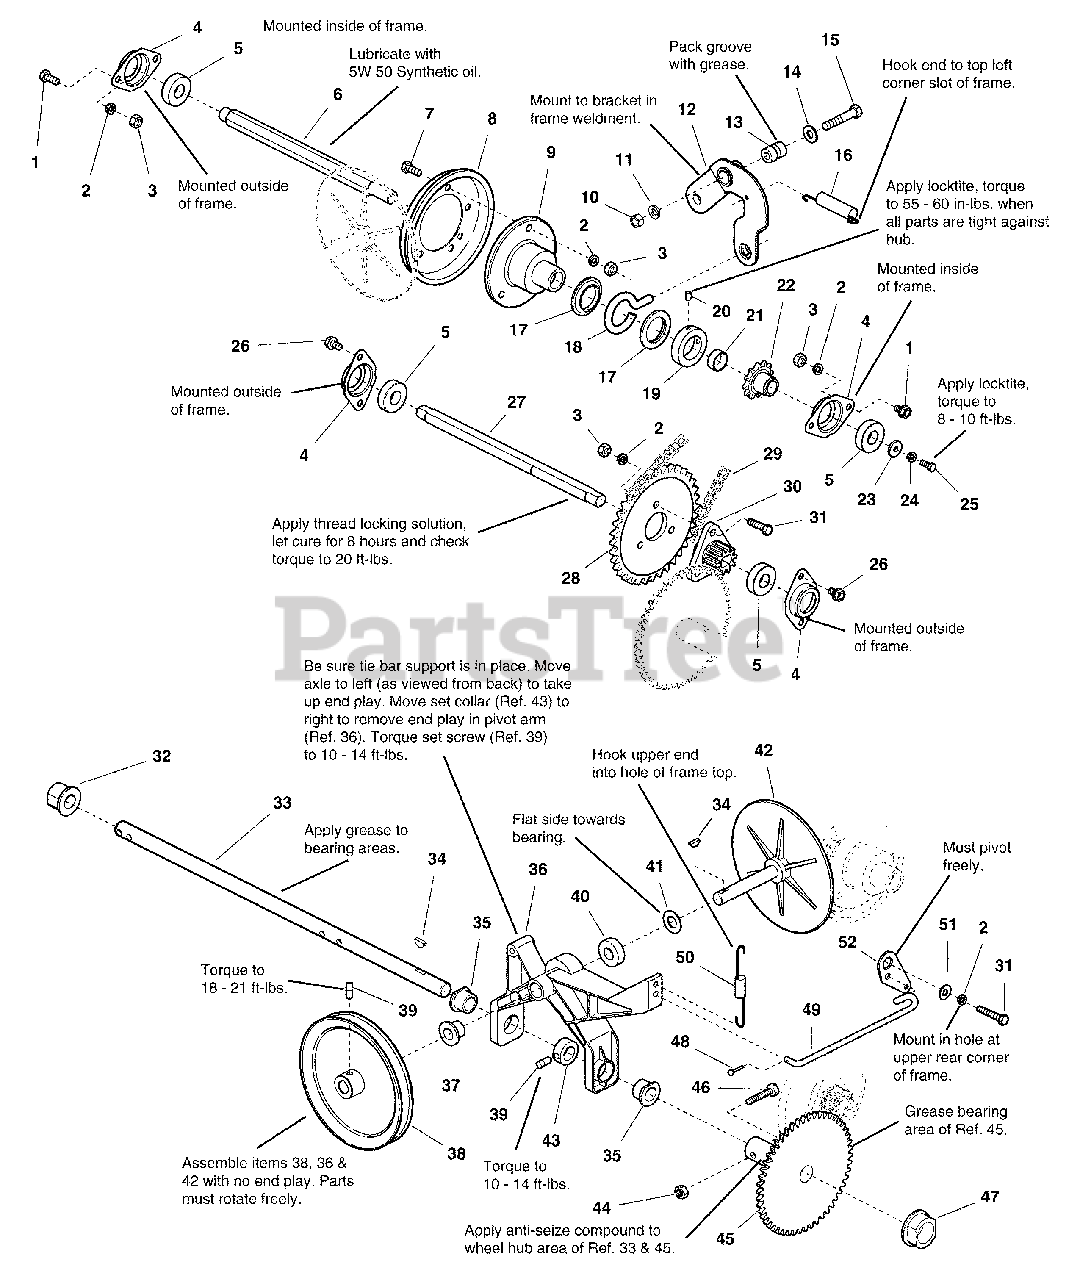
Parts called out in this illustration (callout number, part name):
1	CAPSCREW, Hex Head, 5/16-18 x 5/8
2	LOCKWASHER, 5/16
3	NUT, Hex, 5/16-18
4	RETAINER, Bearing
7	CAPSCREW, Hex Head, 5/16-18 x 3/4
8	DISC, Friction
9	HUB, Friction Disc
10	NUT, Hex, 3/8-16
11	LOCKWASHER, 3/8
12	ARM ASSEMBLY, Shift w/Bushings
13	BUSHING, Spacer
14	WASHER, Flat, 13/32
15	CAPSCREW, Hex Head, 3/8-16 x 2
16	SPRING
17	COLLAR, Thrust
20	SETSCREW, Square Head, 1/4-20 x 1/2
22	SPROCKET, 10 Tooth
23	WASHER, Flat, 1/4
24	LOCKWASHER, 1/4
25	CAPSCREW, Hex Head, 1 /4-20 x 5/8
26	CAPSCREW, Taptite, 5/16-18 x 1/2
28	SPROCKET, 36 Tooth
29	CHAIN, Drive, 40
30	GEAR & BEARING ASSEMBLY., 10 Tooth
31	CAPSCREW, Hex Head, 5/16-18 x 1
34	KEY, Woodruff, 3/16 x 5/8
36	ARM ASSEMBLY, Pivot w/Bushings, (Includes Ref. 35, 37 & 40)
38	PULLEY, Traction
39	SETSCREW, Square Head, 5/16-18 x 1/2
42	DRIVE DISC W/SPINDLE
43	SET COLLAR
44	NUT, Hex, Lock, 5/16-18
45	GEAR & HUB ASSEMBLY, w/Bushing, 50 Tooth
46	CAPSCREW, Hex Head, 5/16-18 x 1-1/2
47	BUSHING, Axle
48	PIN, Cotter, 1/8 x 3/4
51	WASHER, Flat, 11/32
